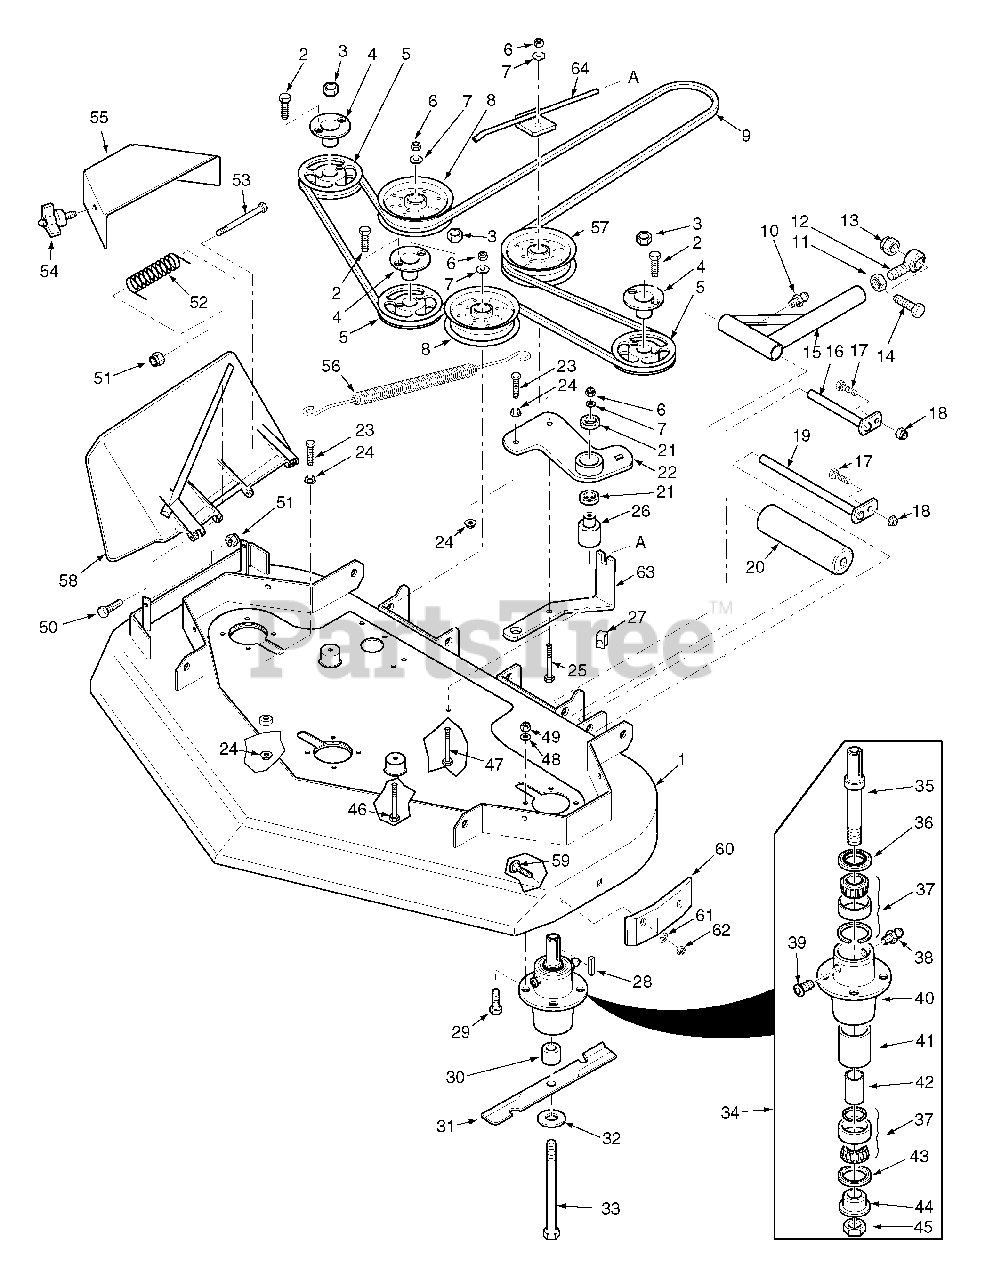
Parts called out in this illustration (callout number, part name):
1	Cutter Deck
3	Nut, 5/8-11
4	Tapered Hub, 1.125" Bore
7	Flatwasher, 3/8-.391 x .938 x .105
8	Pulley, 5" Idler
10	Grease Fitting 1/4-28 Self Tapping
11	Nut, 1/2-20 UNF
12	Rod End, 1/2-20 RH Thread
13	Nut, Elastic Stop 1/2-13
14	Bolt, Hex Head 1/2-13 x 4"
15	Push Arm Assembly
16	Rod Weldment, Push Arm
17	Bolt, Hex Head 5/16-18 x 1"
18	Nut, Serrated Flange 5/16-18
19	Shaft Weldment, Guide Roller
20	Roller
21	Bearing
22	Idler Arm Assembly
23	Bolt, Hex Head 3/8-16 x 1-1/2" Gr. 8
24	Nut, Serrated Flange 3/8-16
25	Bolt, Hex Head 3/8-16 x 3"
26	Pivot, Idler
27	U-Nut, 3/8-16
28	Key, 1/4 x 1/4 x 1"
29	Bolt, 5/16-18 x 1-3/4" Gr. 8
30	Spacer, Spindle
32	Flatwasher, 5/8-.688 x .75 x .134 HD
36	Seal, Top
37	Bearing Assembly
38	Grease Fitting
39	Relief Fitting, Tapered Spindle
40	Spindle Housing
41	Spacer, Outside
42	Spacer, Inside
43	Seal, Bottom
44	Spindle Bushing, Bottom
45	Nut, Special 1 - 1/16-18
46	Bolt, 3/8-16 x 4-1/2"
47	Bolt, 3/8-16 x 3-1/2"
48	Lock washer, 5/16"
49	Nut, Elastic Stop 5/16-18 Gr. 8
50	Bolt, 5/16-18 x 1-1/2"
51	Nut, Elastic Stop 5/16-18
52	Spring, Discharge Chute
53	Bolt, Hex Head 5/16-18 x 4-3/4"
54	Knob w/stud, 3/8-16 x 1-1/4"
55	Belt Cover
56	Spring
57	Pulley, 5" Idler
58	Discharge Chute
59	Bolt, Carr. 5/16-18 x 3/4"
60	Wear Pad
61	Flatwasher
62	Nut, Center Lock 5/16-18
63	Bracket, Belt Guide
64	Rod, Belt Guide
